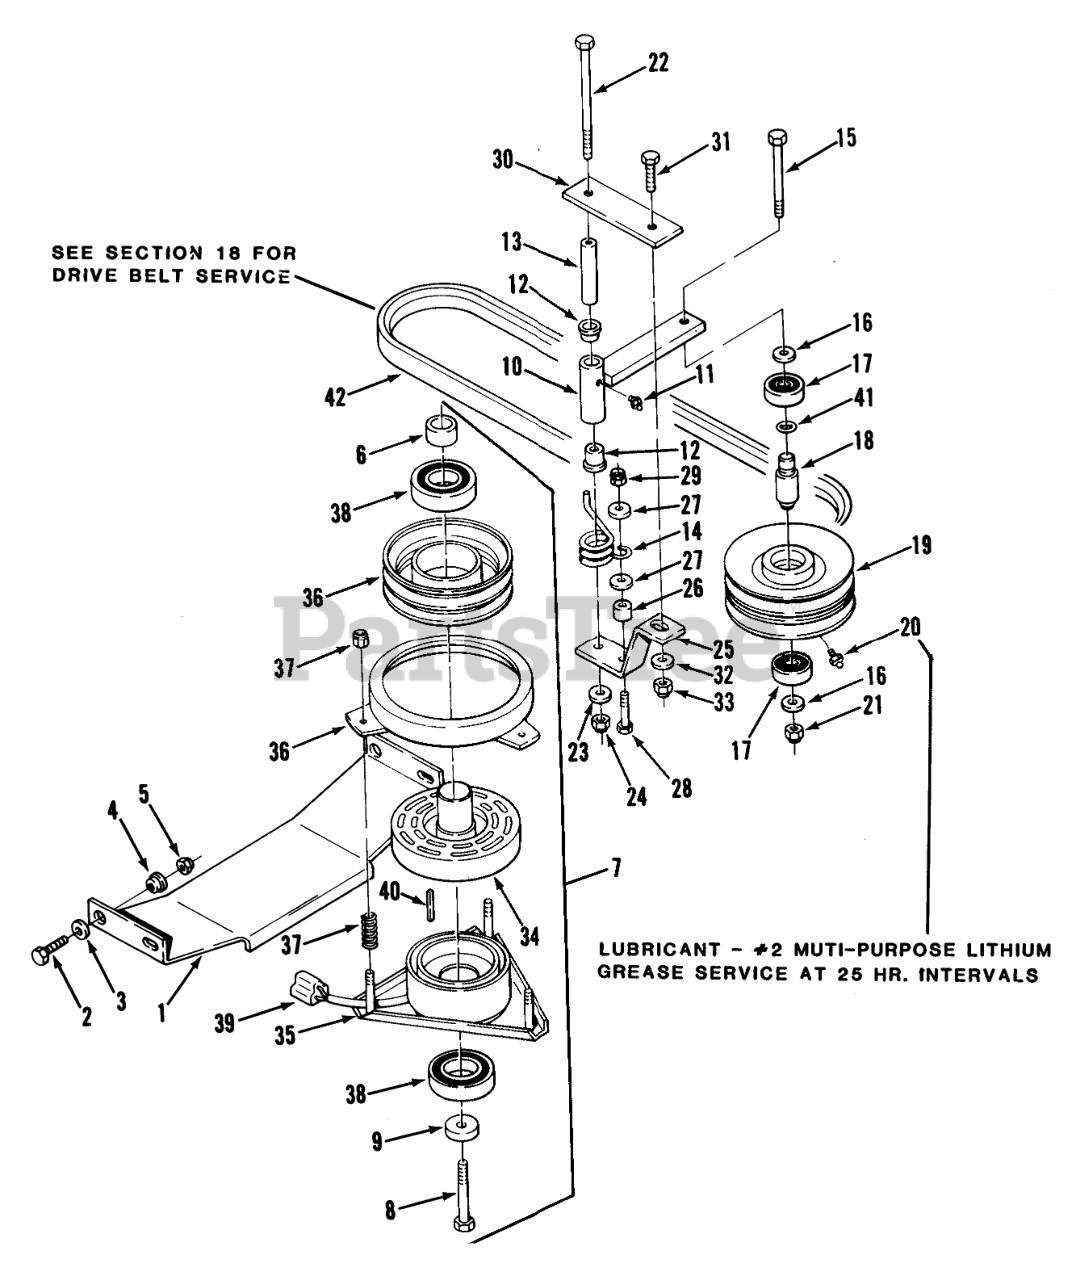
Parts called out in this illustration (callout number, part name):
1	BRACKET CLUTCH ST R
2	HHCS
3	WASHER 5/16 SAE
4	BUSHING
5	Nut
6	SPACER
7	CLUTCH
8	Bolt 7/16-20 x 2 3/4
9	WASHER
10	Arm-Idler
11	Fitting-Grease
12	BUSHING
13	SPACER
14	SPRING-TORSION
15	HHCS
16	Washer
17	BEARING-BALL
18	SPACER-PTO IDLER
19	PULLEY 2- GROOVE
20	Zerk
21	NUT
22	Bolt 3/8-16 x 4
23	Washer
24	NUT
25	Bracket-Idler
26	Spacer
27	Collar
28	Bolt
29	Nut
30	Plate
31	Bolt
32	Washer
33	NUT
34	ROTOR ASSEMBLY
34	ARMATURE ASSEMBLY
35	Field (Includes Bearing) 616-Z
36	Armature and Pulley (Includes Bearing)
37	ACCESS SPRING & NUT
38	BEARING-ELEC CLUTCH
39	CONNECTOR BODY B
41	O RING
42	V-BELT
